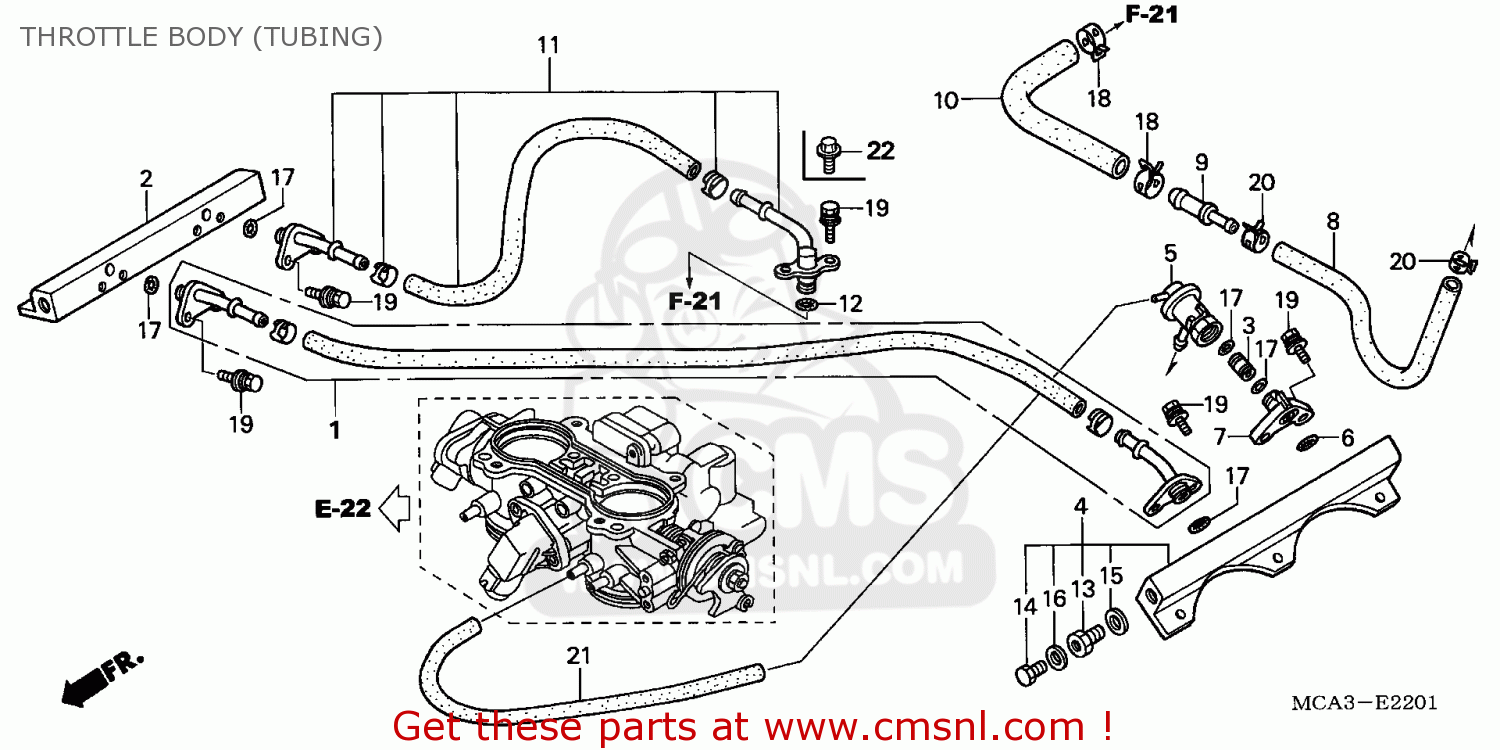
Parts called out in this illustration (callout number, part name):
1	HOSE COMP B,FUEL
2	PIPE COMP,R FUEL
3	JOINT,STRAIGHT
4	PIPE COMP,L FUEL
5	REGULATOR ASSYPRE
6	O-RING,12.1X1.9
7	STAY,P/REG MOUNT
8	HOSE,RETURN FUEL
9	JOINT,FUEL RETURN
10	HOSE,RETURN FUEL
11	HOSE COMP A,FUEL
12	0-RING,7.52X3.53
13	BOLT,BANJO 12MM
14	BOLT SEALING 6MM
15	WASHER,SEALING 12MM
16	WASHER SEALING 6MM
17	O-RING,7.8X1.9
18	CLAMP D12,TUBE
19	BOLT-WASH.,6X16
20	CLAMP D10.5 FUEL
21	TUBE,3.5X290
